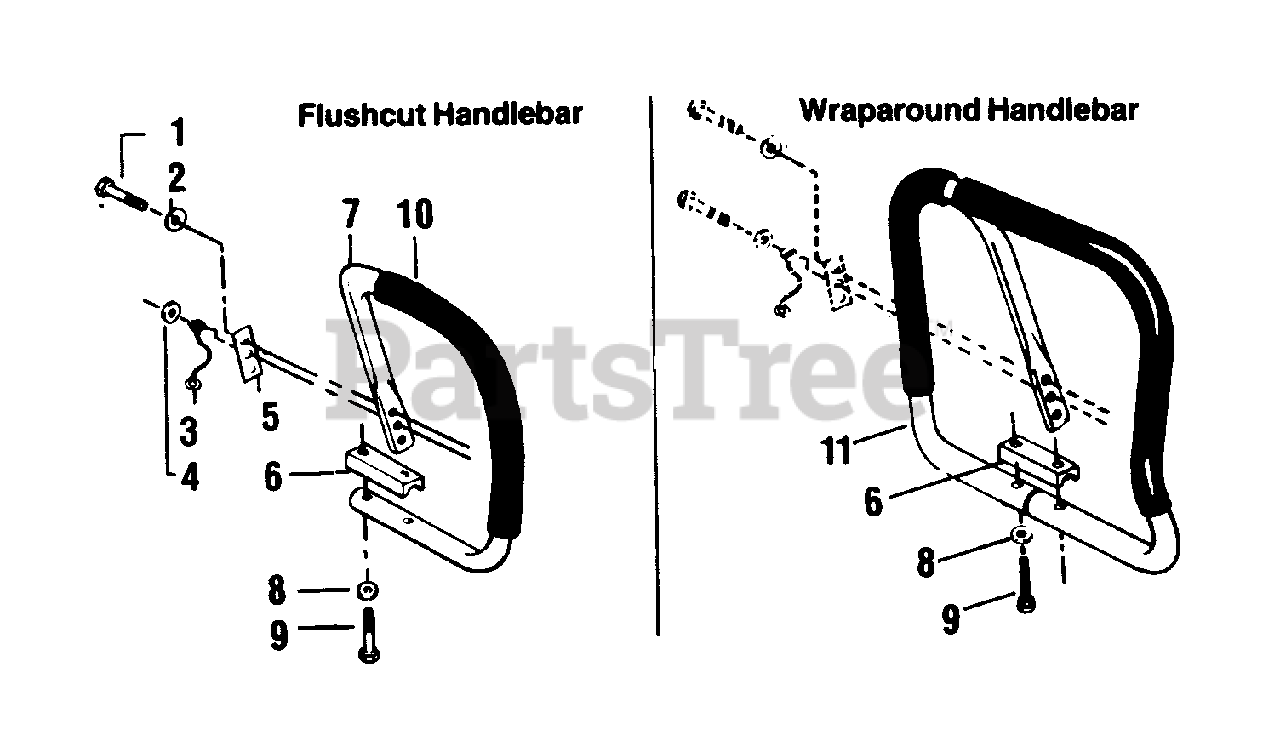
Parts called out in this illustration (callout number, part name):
1	Screw-1/4-20x3/4
2	Lockwasher
3	Lead Ground
4	Washer-Flat
5	Handlebar Brace-Rear
6	Adaptor-Handlebar
7	Handlebar-Flushcut
8	Washer-Conical
9	Screw-1/4-20x1-3/8
10	Kit-Handlebar Grip
11	Kit - Wraparound Handlebar - Optional (Incl. #25, 42 & 43 from p.3)
